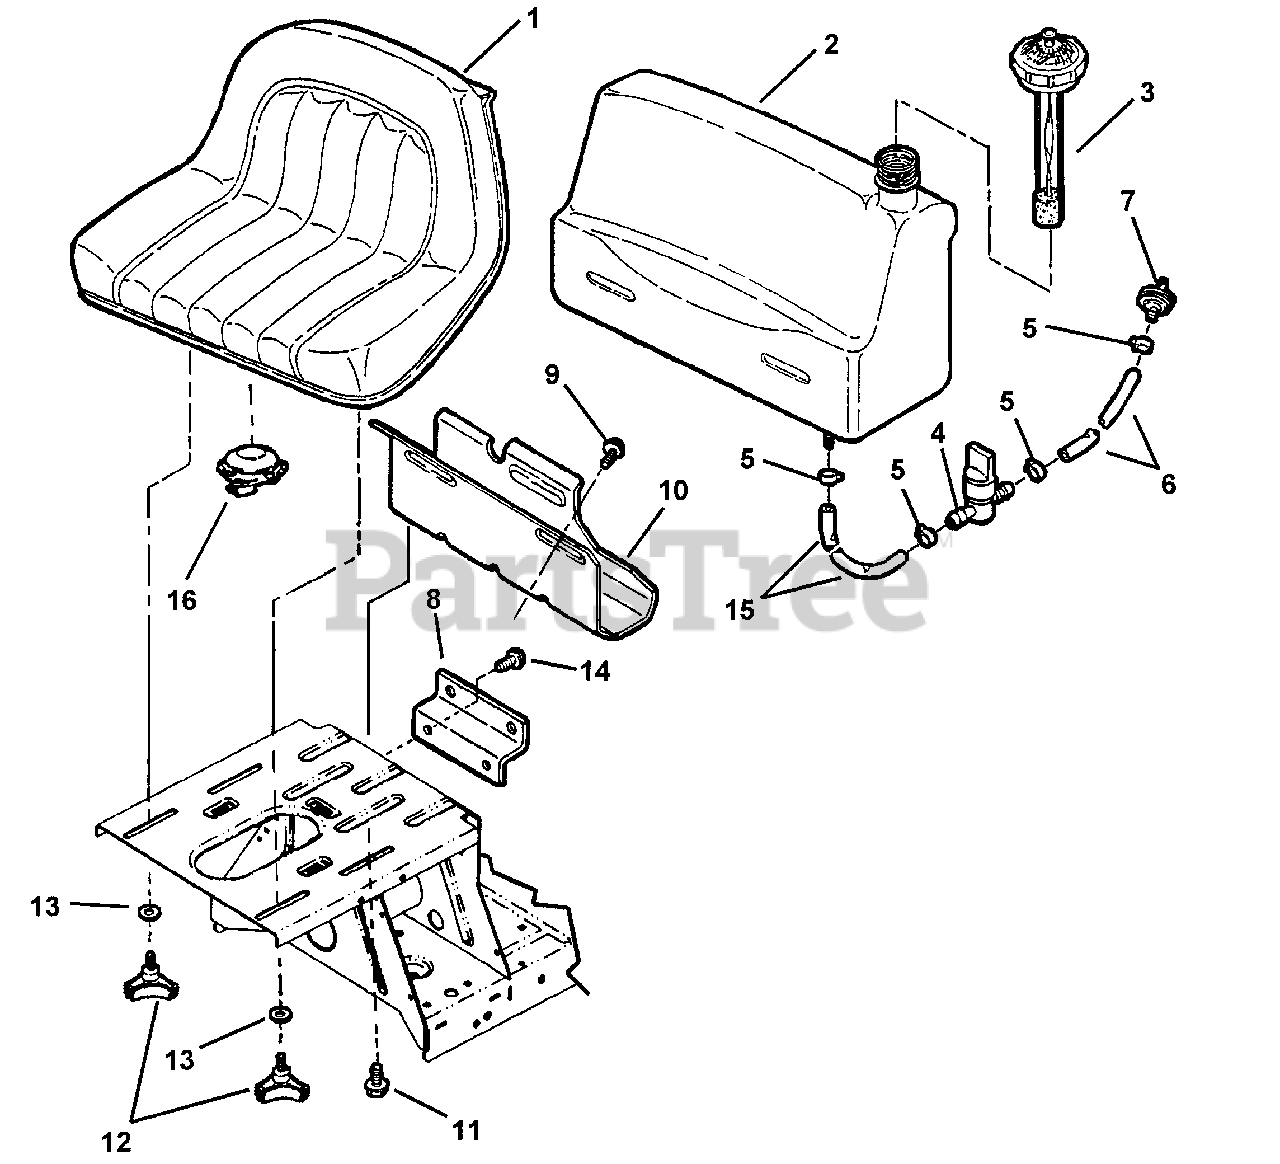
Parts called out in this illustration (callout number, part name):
1	SEAT, Operator (Deluxe Back)
2	ASSEMBLY, Fuel Tank
3	CAP, Fuel Tank (With Gauge)
4	VALVE, Fuel Shut-Off
5	CLAMP, Fuel Line
6	HOSE, Fuel (5" Long)
7	FILTER, Fuel (In-Line)
8	BRACKET, Tank
9	SCREW, 5/16-18 x 5/8" Self-Tap
10	BRACKET, Fuel Tank (Rear)
11	BOLT, 5/16-18 x 1/2" Hex Fl. Lock
12	KNOB, Seat Adjusting
13	SPACER, 5/16"
14	SCREW, 5/16-18 x 1/2" Hex Self-Tap
15	HOSE, Fuel (24-1/4" Long)
16	SWITCH, Seat (Normally Closed)
